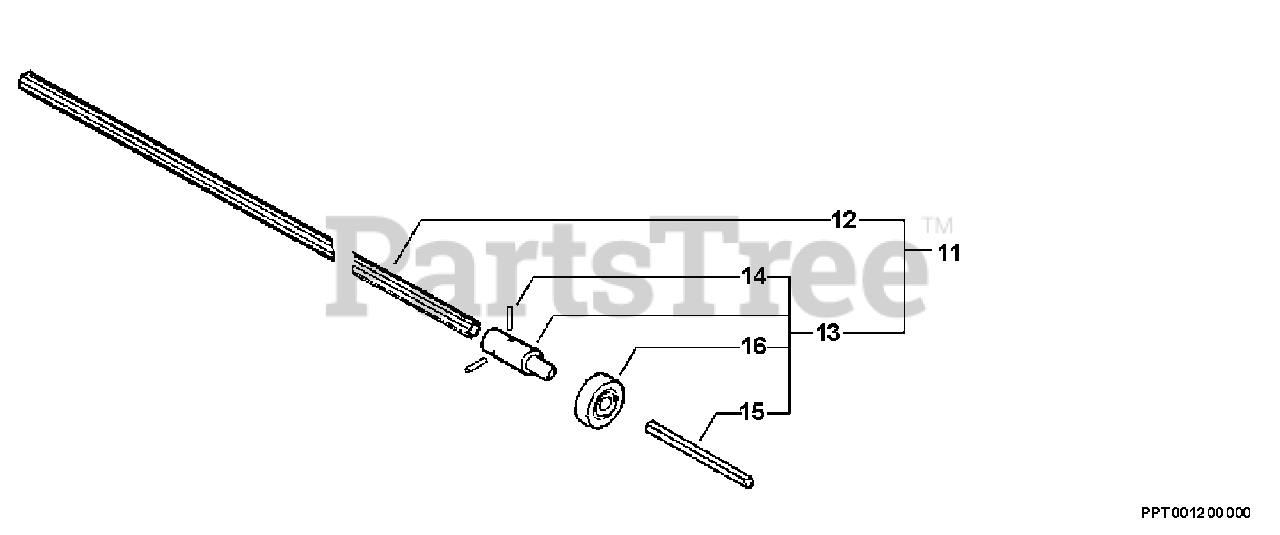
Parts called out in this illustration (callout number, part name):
11	DRIVESHAFT ASSY
12	DRIVESHAFT
13	SHAFT CONNECTOR KIT
16	BEARING, BALL - 6002
